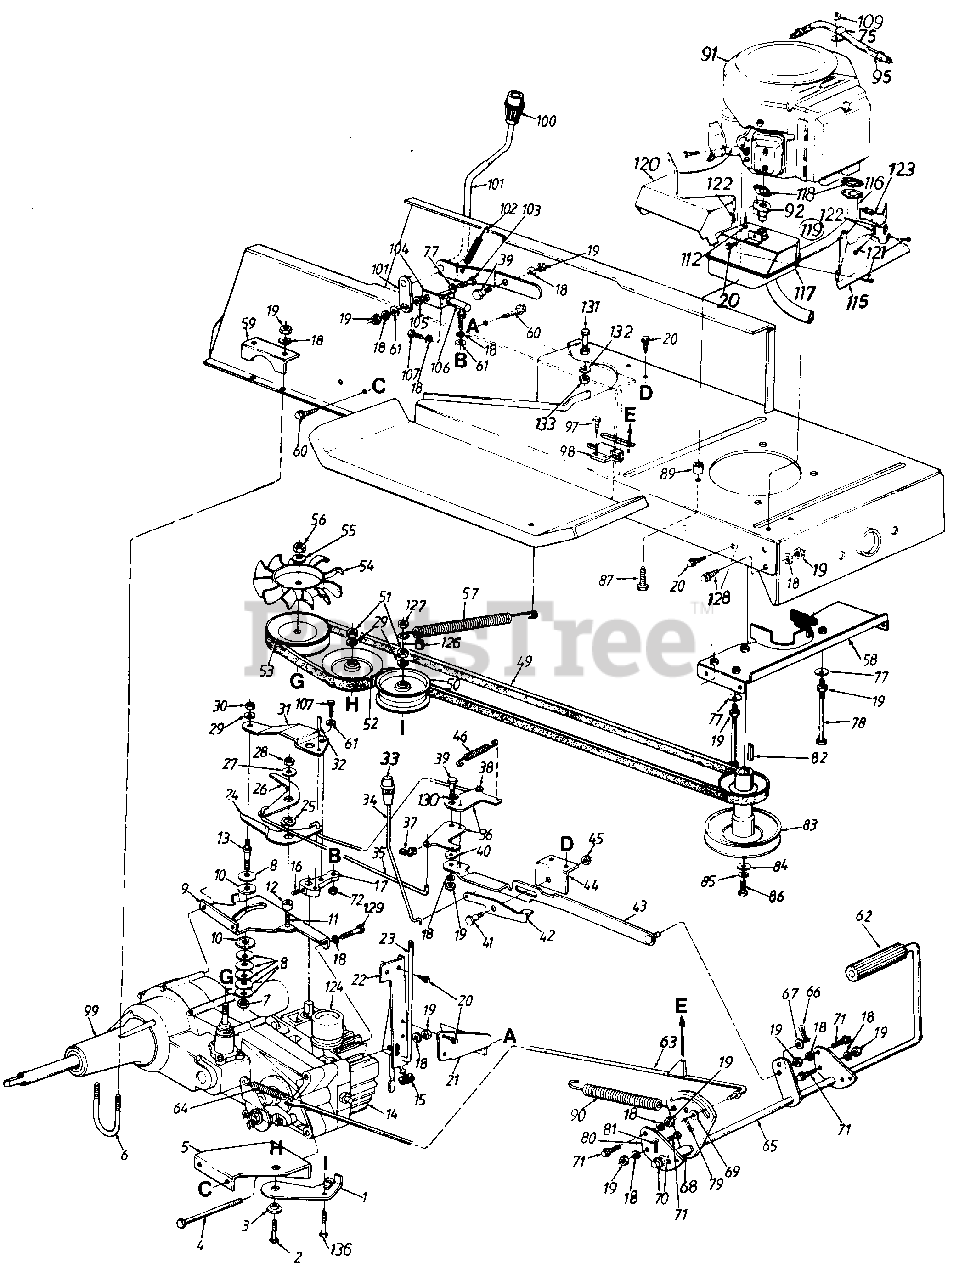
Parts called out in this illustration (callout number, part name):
1	Idler Bracket
2	Hex Bolt 318-16 x 2.0" Lg.
3	Shld. Spacer.625" l.D.
4	Hex Bolt 5/16-18 x 4,5h Lg. (Gr. S)
5	Idler Plate
6	U-Bolt 5/16-18 x 1.75" Lg.
7	Hex L-Nut 318-24 Thd.
8	Bell-Wash. .40" l.D. x 1.13"
9	Mounting Bracket
10	Friction Washer
11	Rib Neck Bolt 5116-24 x .84" Lg.
14	Hydrostatic Pump
15	Rubber Washer .33" I.D.
17	Pintle Shitt Lever
18	L-Wash. 5/16" l.D.
19	Hex Nut 5/16-18 Thd.
20	Hex TT-Tap Scr. 1/4-20 x .5"
21	Reintorcement Plate
22	Transmission Torque Brkt.
23	Release Valve Rod
24	Reverse Arm
25	Spring Washer .625" I.D.
26	Forward Arm
27	Fl-Wash. .344" I.D. x 1.0"
28	Hex Cent. L-Nut 5/16-24 Thd.
29	L-Wash. 3/8" I.D.
30	Hex Nut 3/8-24 Thd.
31	Pintle Arm Ext. Plate
32	Roll Pin 1/4" Dia. x .75" Lg.
33	Knob
35	Connection Rod
36	Balancer Bracket
37	Rod End Clevis Clips-R.H.
38	Rod End Clevis Clips-L.H.
39	Shld. Bolt .437" Dia. x .268"
40	Fl-Wash. .344" l.D. x 1.12"
41	Shld. Bolt .437" Dia. x .35"
42	Lock-Up Bracket
43	Neutral Return Brkt. Ass'y.
45	Hex Cent. L-Nut 5/16-18 Thd.
46	Ext. Spring 2.5" Lg.
49	"V"-Belt
51	Hex Nut 318-16 Thd.
52	Idler Pulley 4.0" O.D.
53	Transmission Pulley
55	Bell-Wash. .56" I.D. x 1.125"
56	Hex Jam Nut 9/16-18 Thd.
57	Extension Spring
58	Belt Guard Brkt. Ass'y.
59	Bracket
60	Hex B-Tap Scr. 5/16-18 x .5"
61	Flat Tooth Washer 5116" I.D.
62	Foot Pad
63	Brake Rod Ass'y.
64	Ext. Spring 3.67" Lg.
65	Clutch Brake Pedal Ass'y.
66	Intern. Cotter Pin 5/16" Dia.
67	Fl-Wash. .385" I.D. x .62"
68	Spacer.63" I.D.
69	Fl-Wash. .385" I.D. x .62"
70	Fl-Wash. .635" I.D. x 1.0"
71	Hex TT-Tap Scr. 5/16-18 x 7/8"
77	Bell-Wash. .345" I.D. x .88"
78	Hex Bolt 5/16-18 x 4.0" Lg.
79	Cotter 3132" Dia. x 75" Lg.
80	Pedal Brkt.
81	Cotter Pin 3/32" Dia. x 1.0" Lg.
82	Sq.-Key 1/4" x 2.0"
83	Engine Pulley
84	Fl-Wash. 7/16" l.D. x 1.25"
85	L-Wash. 7/16" I.D. (H.D.)
86	Hex Bolt 7/16-20 x 1.5" Lg.
87	Hex TT-Tap Scr. 3/8-16 Thd
89	Spacer 5/16" l.D.
90	Extension Spring 6.11" Lg.
91	Engine
92	Inlet Tube Ass'y.
95	Hydraulic Hose 13" Lg.
97	Hex Tap Scr. #10 x 318"
98	Safety Switch
101	Speed Selector Lever Ass'y.
102	Ext. Spring 2.75" Lg.
103	Hex Bolt 5/16-18 x 1.25" Lg.
104	Connection Brkt.
105	Shoulder Nut
106	Ball Joint 5/16-24 Thd.
107	Hex Bolt 5/16-24 x .75" Lg.
109	Hex Jam Nut 3/8-16 Thd.
112	Bolt w/Washer
115	Muffler Heat Shield-Front
116	Formed Tube Ass'y.
117	Exhaust Muffler Sub Ass'y.
118	Gasket
119	Muffler Ass'y. Comp.
120	Muffler Heat Shield
121	Hex Wash. Tap Scr. #10 x 5" Lg.
122	Speed Nut #10-24 Thd.
123	Front Heat Shield Ext.
124	Reservoir
126	Spacer .375" I.D. x .503
127	Hex Jam Nut 3/8-16 Thd.
128	Hex Wash. TT-Tap Scr. 5/16-18 x .62" Lg.
129	Hex olt 5/16-18 x 4.7Sn Lg.
130	Spr.-Wash. .445" l.D. x .75" O.D.
131	Hex Bolt 1/4-20 x 1.25 Lg.
132	L-Wash. 1/4" l.D.
133	Hex Nut 1/4-20 Thd.
136	Hex Bolt 3/8-16 x 2.5" Lg.
